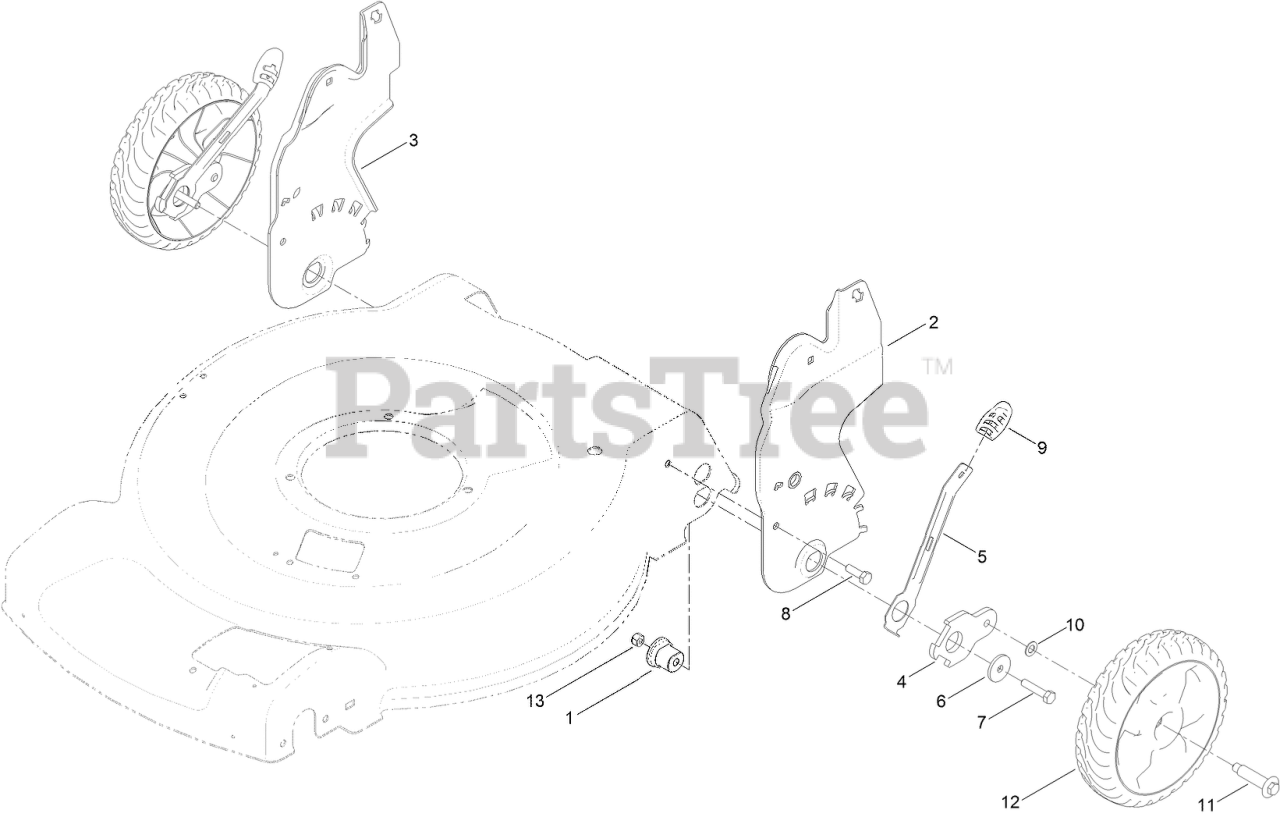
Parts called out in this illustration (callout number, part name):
1	BUSHING-MOUNT, HOC
2	PLATE-HOC, LH
3	PLATE-HOC, RH
5	ARM-SPRING, REAR
6	WASHER-FLAT
7	SCREW-HH
8	SCREW-HH
9	KNOB-LEVER, HOC
10	WASHER
11	BOLT-SHOULDER
13	NUT-LOCK, NI
